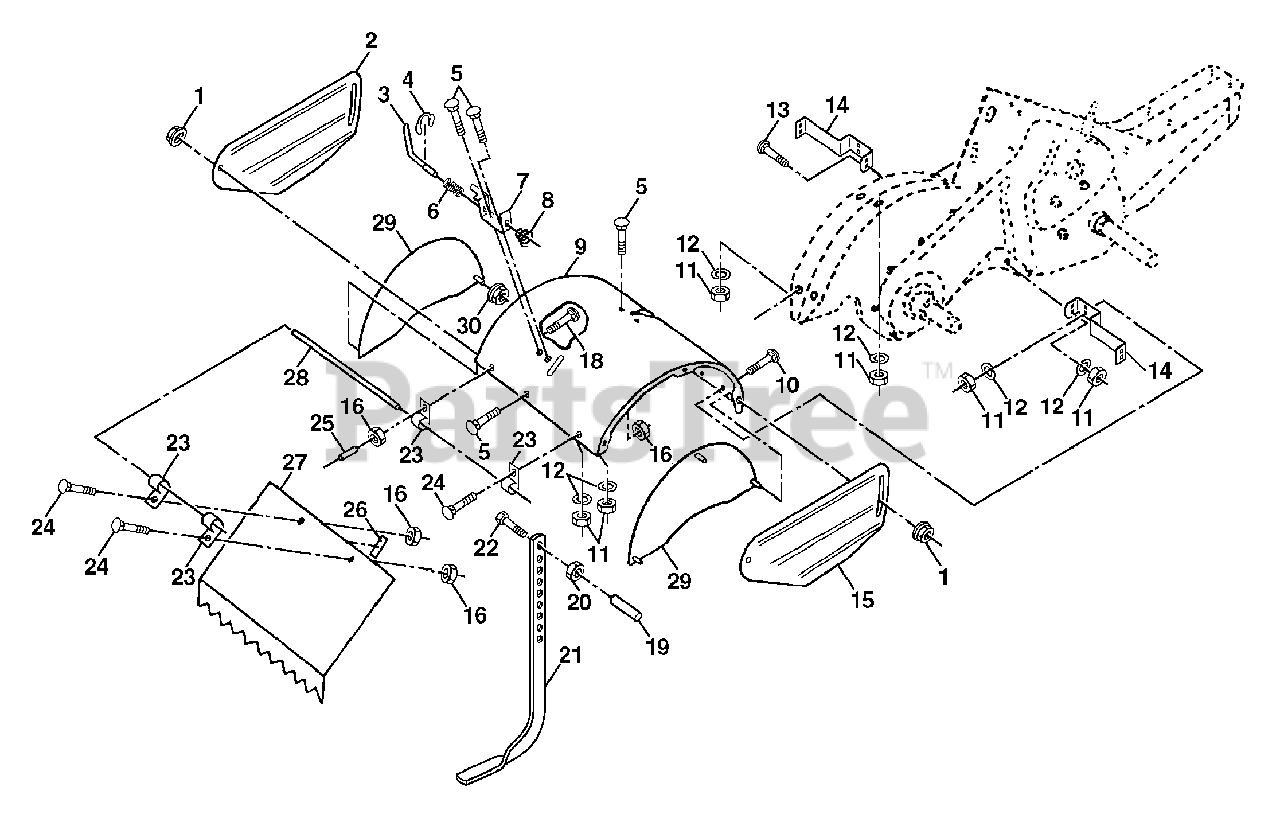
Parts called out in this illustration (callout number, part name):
1	Nut, Flange 5/16-18
2	Shield, Side, Outer L. H.
3	Pin, Stake, Depth
4	Ring, Klip
5	Bolt, Carriage 5/16-18 x 3/4 Gr. 5
7	Bracket, Latch
8	Spring, Depth Stake
9	Shield, Tine
10	Bolt, Carriage 5/16-18 UNC x 1
11	Nut, Hex 5/16-18
12	Washer, Lock 5/16
13	Bolt, Carriage 5/16-18 x 1-1/4
14	Bracket, Shield Tine
15	Shield, Side, Outer R.H.
16	Nut, Keps Hex 1/4-20
17	Washer, Lock 1/4
18	Bolt, Carriage 1/4-20 x 1-1/4 Gr. 5
20	Nut, Hex 3/8-16
21	Stake, Depth
22	Bolt, Hex 3/8-16 x 2
24	Bolt, Carriage 1/4-20 x 1/2 Gr. 5
25	Cap, Vinyl
26	Pad, Idler
27	Shield, Leveling
28	Pin, Hinge
29	Shield, Side
30	Locknut, Flange 5/16-18
